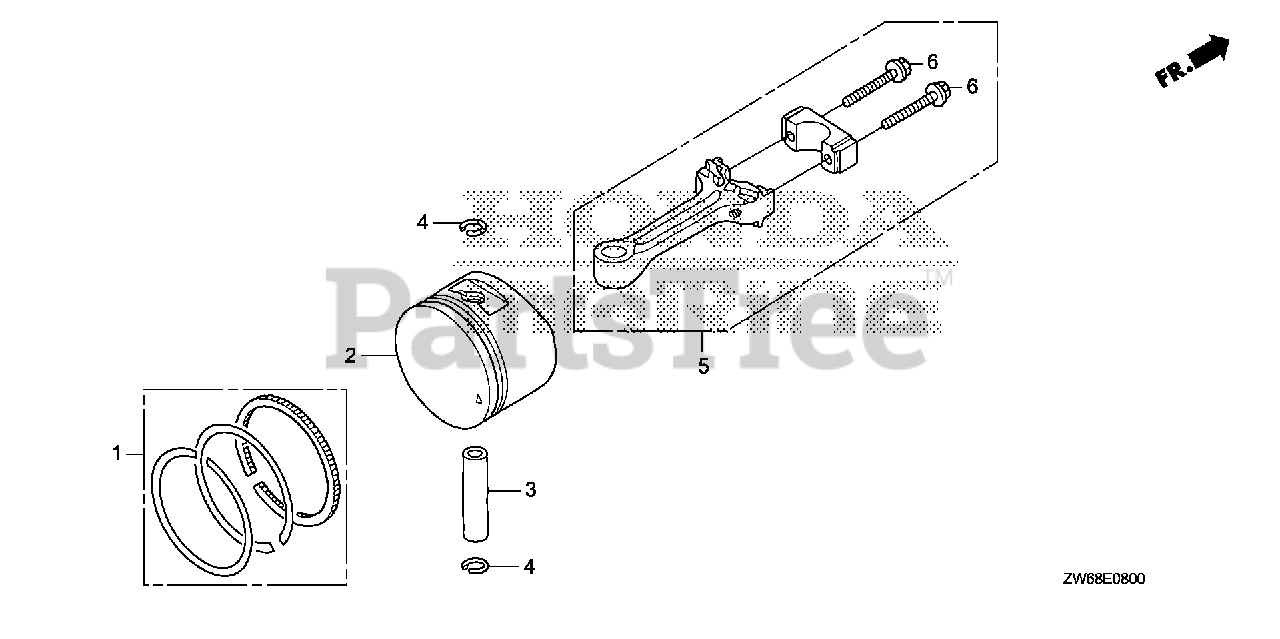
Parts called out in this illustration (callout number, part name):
1	RING SET, PISTON (STD)
2	PISTON (STD)
3	PIN, PISTON
4	CLIP, PISTON PIN (10MM)
5	ROD ASSY., CONNECTING
6	BOLT, CONNECTING ROD
